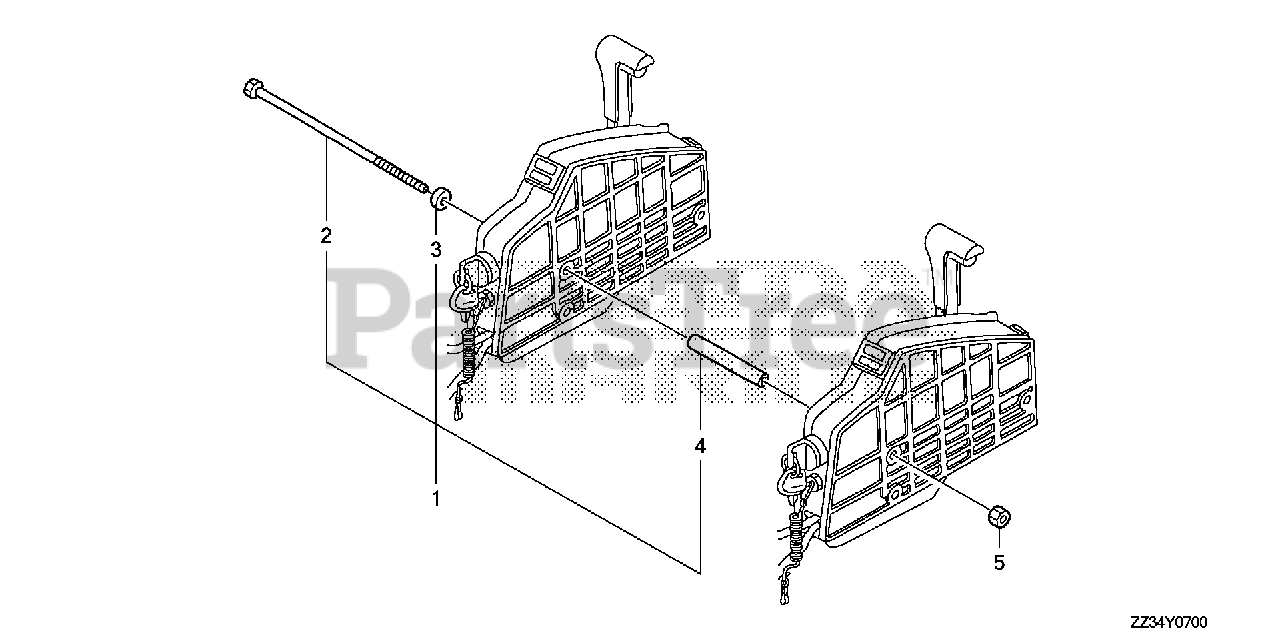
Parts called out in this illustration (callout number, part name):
1	BOLT KIT, SIDE REMOTE CONTROL
2	BOLT, SPECIAL (6X220)
3	COLLAR, DISTANCE (A)
4	COLLAR, DISTANCE (B)
5	NUT, HEX. (6MM)
